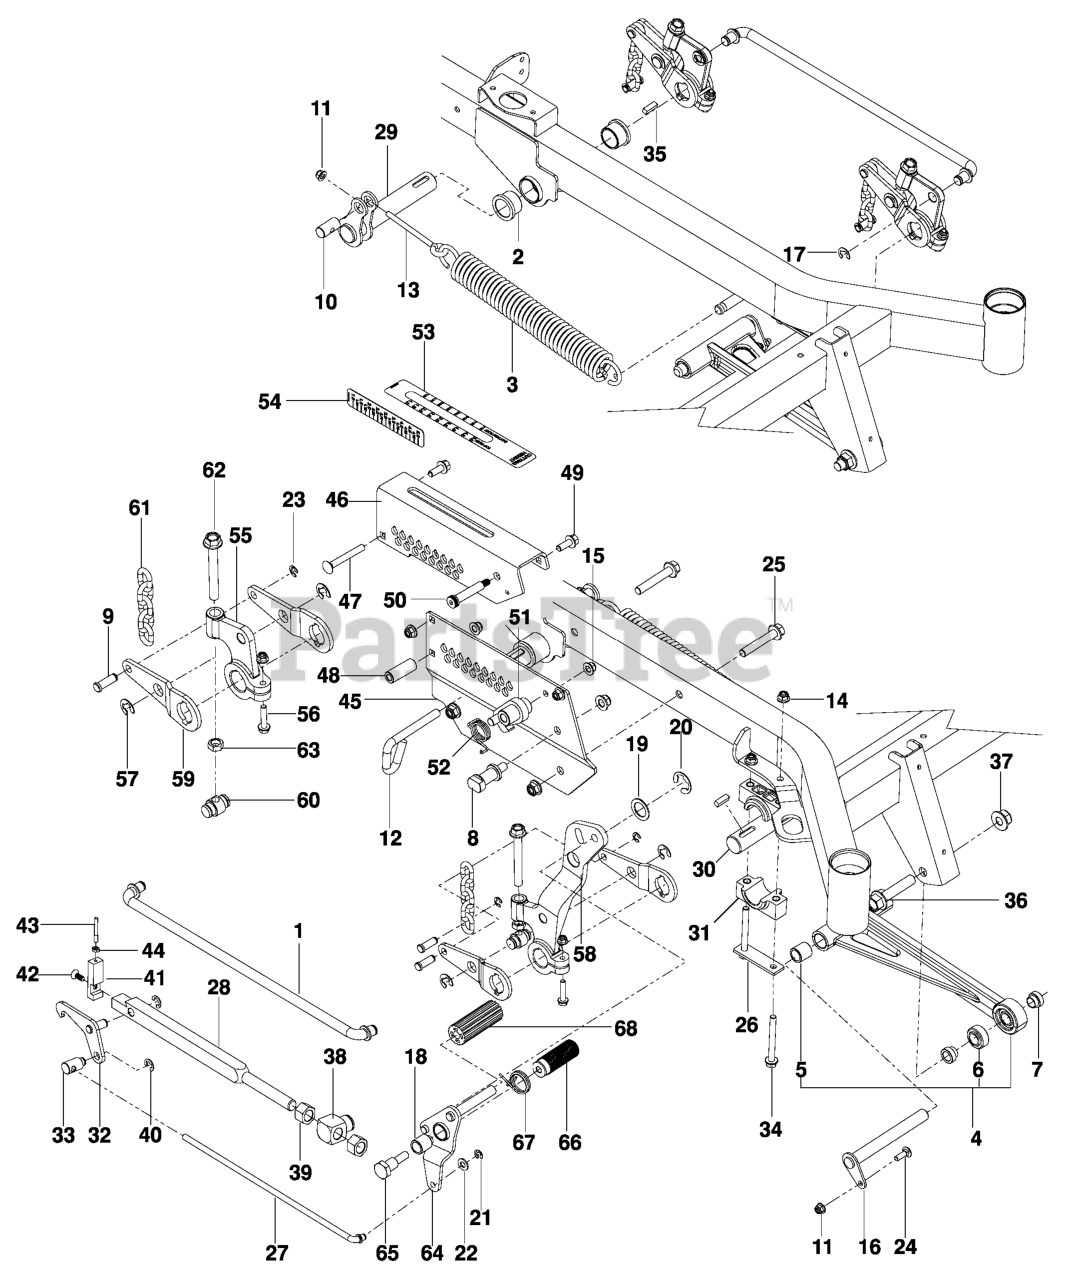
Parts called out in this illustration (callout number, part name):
1	ROD, LIFT
2	BUSHING, FLANGE 1.25 X 1.0
3	SPRING, EXTENSION
4	ASSEMBLY, STRUT
5	BUSHING, SLEEVE 3/4 X 1.0
6	BALL JOINT, 3/4" SWIVEL
7	SPACER, STRUT
8	GUIDE, HEIGHT BAR
9	PIN, 7/16 CLEVIS
10	PIVOT, SPRING
11	5/16-18 NYLOC FLANGE NUT
12	PIN, HEIGHT
13	EYE BOLT 4.5`
14	NUT 3/8-16 HEX FLG NYLOC ZD
15	NUT, 1/2-13 HEX FLG NYLOC ZD
16	PIN, STRUT
17	E-RING 5/8
18	BUSHING, SLEEVE 3/4 X 1.0
19	MACHINE BUSHING
20	E-RING 1"
21	E RING 3/8"
22	WASHER 3/8 SAE FLAT
23	RING, E, 7/16
24	RHSNB 5/16C X 1
25	HFFS 1/2-13 X 3 GD 5 ZD
26	PLATE, PILLOW BLACK
27	ROD, HEIGHT LATCH
28	BAR, HEIGHT
29	SHAFT, RR LIFT
30	SHAFT, LIFT, FT
31	BLOCK, PILLOW
32	LATCH, HEIGHT WLDMT
33	SWIVEL, HEIGHT LATCH
34	HHFS 3/8-16 X 3.5 GD 5 ZD
35	KEY, 5/16 SQ X 1.0
36	HHFS 5/8-11 X 3.0 GD 8 ZD
37	NUT 5/8-11 FLG NYLOC ZD
38	SWIVEL, HEIGHT BAR
39	NUT 3/4-10 HEX ZD
40	E-RING 1/2 (2 2)
41	CAP, HEIGHT BAR
42	SCREW, 5/16-18 X 3/4 FLAT HEX
43	LINK, INDICATOR
44	NUT 1/4-20 JAM
45	PLATE, INNER HEIGHT, ORANGE
46	PLATE, OUTER HEIGHT ORG
47	3/8-16 X 3` CARR BOLT
48	SPACER, HEIGHT PLATE
49	HHFS 3/8-16 X 1 GRD 5 ZD
50	BOLT, SHOULDER, 1/2 X 2.25
51	LATCH, TRANSPORT WLDMT
52	SPRING, TORSION
53	DECAL, HEIGHT
54	DECAL, HEIGHT
55	ARM, CAST LIFT
56	HHFS 5/16-18 X 1.5 GD 5
57	E RING 3/4
58	ARM, LIFT LEVER
59	ARM LIFT BLK
60	SHAFT, LIFT TRUNION WSL
61	LIFT CHAIN
62	HHFS 1/2-13 X 4 GR 5
63	NUT 1/2 HEX JAM
64	PEDAL, RELEASE WLDMT
65	BOLT, SHOULDER
66	PAD, FOOT PEDAL
67	SPRING, TORSION
68	PEDAL, DECK HEIGHT
